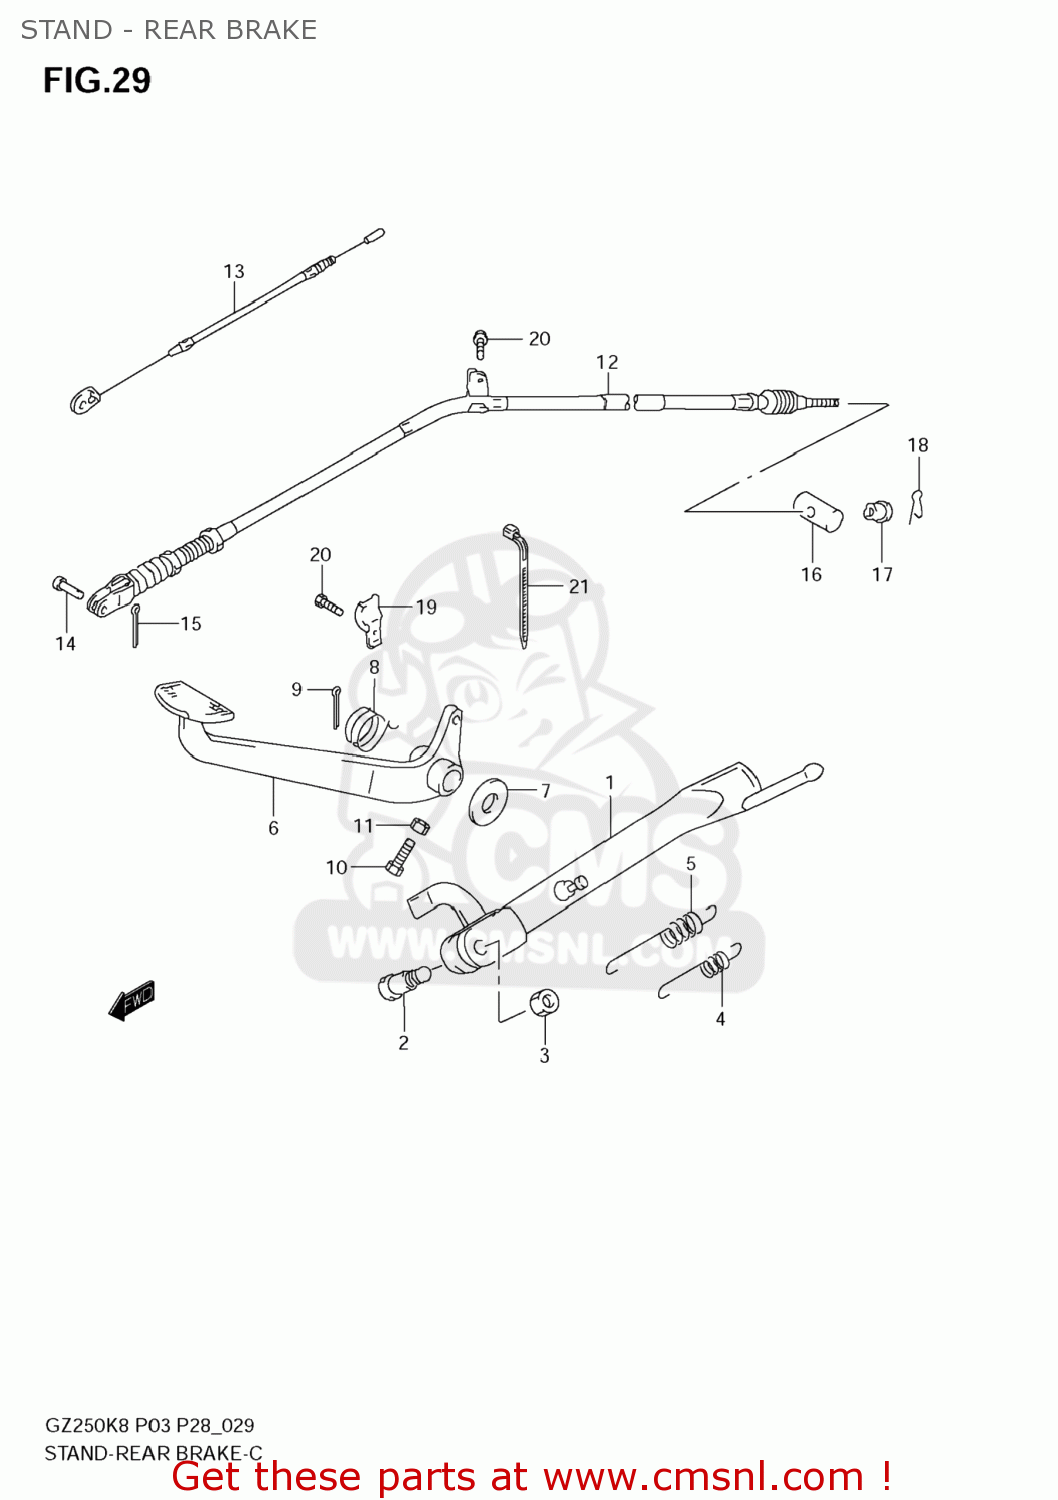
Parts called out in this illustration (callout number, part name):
1	STAND,PROP
2	BOLT(10X34)
3	NUT
4	SPRING
5	SPRING
6	PEDAL, BRAKE
7	WASHER(16.5X22X1)
8	SPRING
9	PIN
10	BOLT
11	NUT
12	CABLE,RR BRAKE
13	CABLE,STOP LAMP SWITCH
14	PIN(L:17.5)
15	PIN
16	PIN
17	NUT
18	CLIP
19	GUIDE,RR BRAKE CABLE
20	BOLT
21	CLAMP(L:145)
